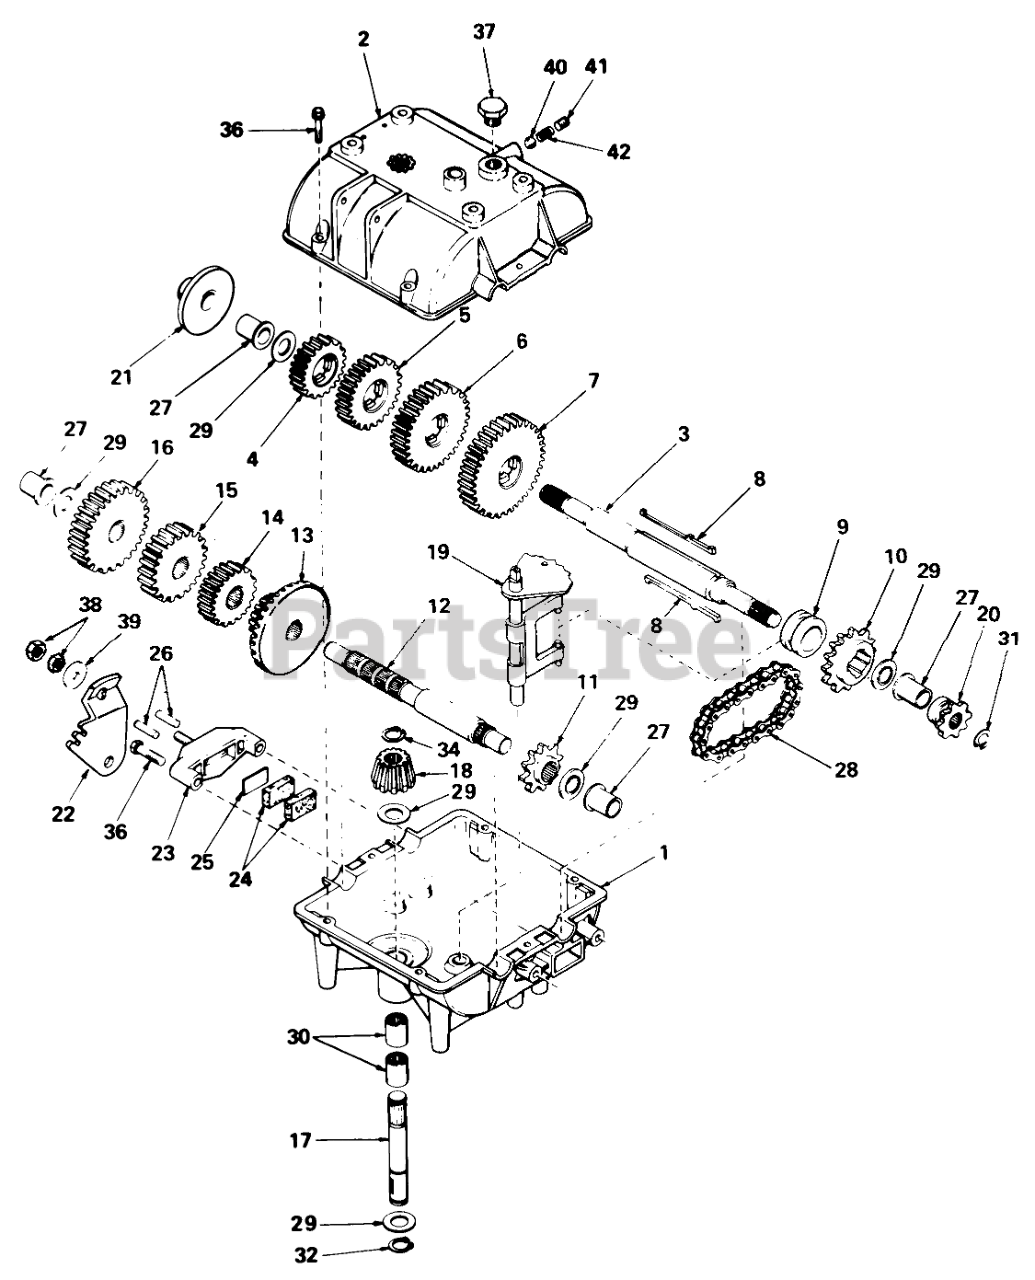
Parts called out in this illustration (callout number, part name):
1	Case-Transmission
2	Cover, Transmission
3	Shaft, Output Brake
4	Gear, Spur (20 Teeth)
5	Gear, Spur (25 Teeth)
6	Gear, Spur (30 Teeth)
7	Gear, Spur (35 Teeth)
9	Collar-Shift
10	Sprocket (14 Teeth)
11	Sprocket 10t
12	Countershaft
13	Gear-Bevel (42 tooth 15 tooth spur gear)
14	Gear, Spur (20 Teeth)
15	Gear, Spur (25 Teeth)
16	Gear, Spur (30 teeth)
17	Shaft, Input
18	Bevel Pinion, Input
19	Rod Fork Assy, Shifter
20	Sprocket (8Teeth)
22	Lever, Brake
23	Holder-Brake Pad
24	Brake Pad
25	Brake Pad Plate
26	Dowel Pin
27	Bushing, Flanged
28	Chain, Roller (#41 Chain, 22 Links)
29	Washer
30	Bearing, Needle
31	Piston Asm (.020 O S)
32	Ring-Snap
34	Ring-Retainer
36	Ring Set (.020 O S)
38	Locknut
39	Washer
40	Ball-Steel
41	Screw-Set
42	Spring
